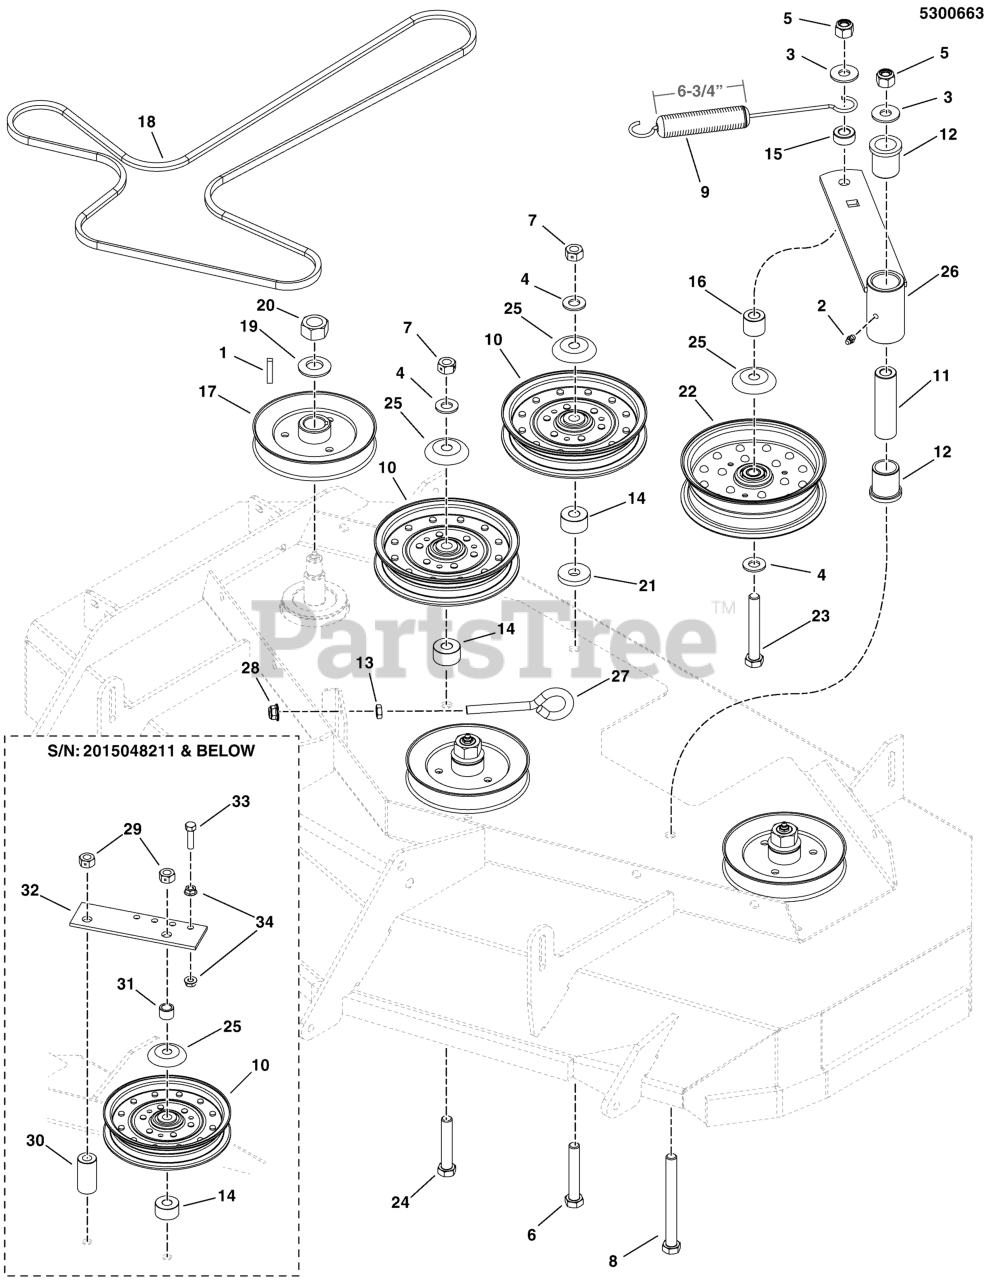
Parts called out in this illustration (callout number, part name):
1	KEY, 1/4" SQ. X 1-1/4
2	GREASE FITTING, 1/4-28 Straight
3	WASHER, 1/2" USSZ
4	WASHER, 1/2 SAE
5	NUT, 1/2-13 HEX NYLON LOCK
6	BOLT, 1/2-13 X 3" GD5 CZ
7	NUT, 1/2-13 Hex Side Lock
8	BOLT, 1/2-13 X 5" GD5 YZ
9	SPRING-EXT, 1.04 ODX10.535LGX.148WR, BLK
11	SPACER, .52 x 1.00 x 3.50
12	BUSHING, FLANGE
13	NUT, 3/8-16 HEX JAM
14	SPACER, .52 X 1.25 X .70, PM, CZ
15	SPACER, .52 X 1.00 X .44, CZ
16	SPACER, .52 X 1.00 X .88, PM, CZ
17	PULLEY, 5.540OB X .985ID, SINGLE B-SEC
18	BELT, BP-SEC, 147.40EL, ARAMID, WRPD
19	WASHER, 3/4 BELLEVILLE CL/ZC
20	NUT, 3/4-16 Hex
21	WASHER, .53 X 1.50 X .25
21	PULLEY, IDLER, 6.75 OD X 1.62 FACE
23	BOLT, 1/2-13 X 3-1/2, HEX HD, GD5, CZ (SV)
24	BOLT, 1/2-13 X 2-3/4 GD5 CZ
25	SHIELD, PULLEY BEARING, CZ
26	ASSM, IDLER ARM
27	EYE BOLT, 3/8-16 X 6, 3THRD, 1EYE, CZ
28	NUT, 3/8 - 16 HEX NYLOCK FLANGE
29	NUT, 1/2-13 Hex Side Lock
30	SPACER, .50 X 1.00 X 2.00
31	SPACER, .51 X .75 X .56, PM, CZ
32	PLATE, SPRING ANCHOR - RED
33	BOLT, 5/16-18 X 1-1/4" GD5 YZ
34	NUT, 5/16-18 HEX SERRATED FLANGE (SMALL)
